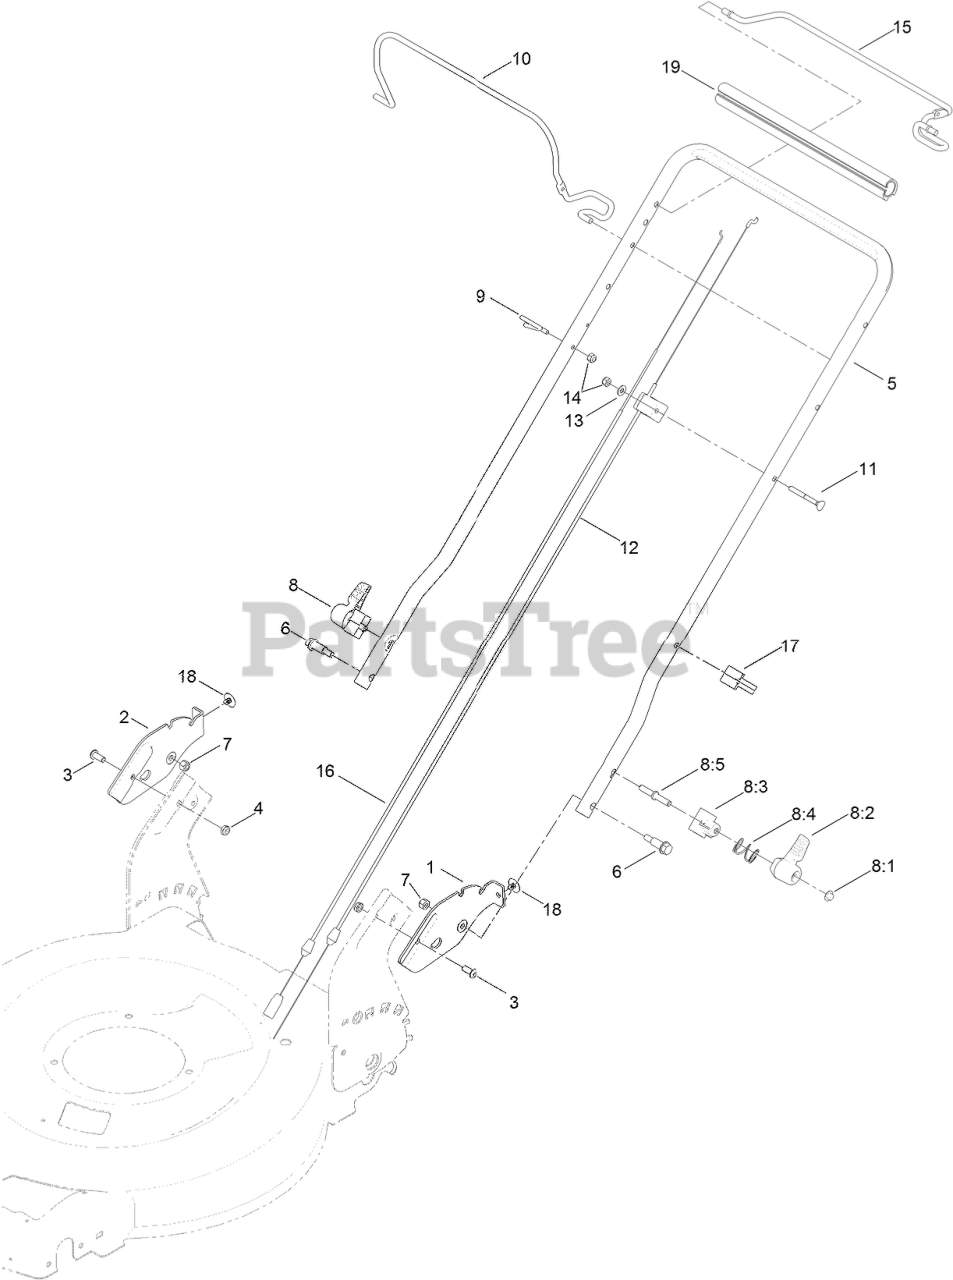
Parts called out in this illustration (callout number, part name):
1	PLATE-HANDLE, LH
2	PLATE-HANDLE, RH
3	SCREW-HSBH
4	NUT-LOCK, NI
6	BOLT-SHOULDER
7	NUT-LOCK, NI
8	QUICK RELEASE ASM
8:1	NUT-PUSH
8:2	LEVER
8:3	ANCHOR-SPRING
8:4	SPRING-COMPRESSION
8:5	ROD-RELEASE
9	GUIDE-ROPE
10	BAIL-BRAKE
11	SCREW-HANDLE
12	CABLE-BRAKE
13	WASHER-FLAT
14	NUT-LOCK, NI
15	BAIL-TRACTION
16	CABLE-TRACTION
17	GUIDE-CABLE
18	CLIP-TREE
19	GRIP-HANDLE, COMFORT
